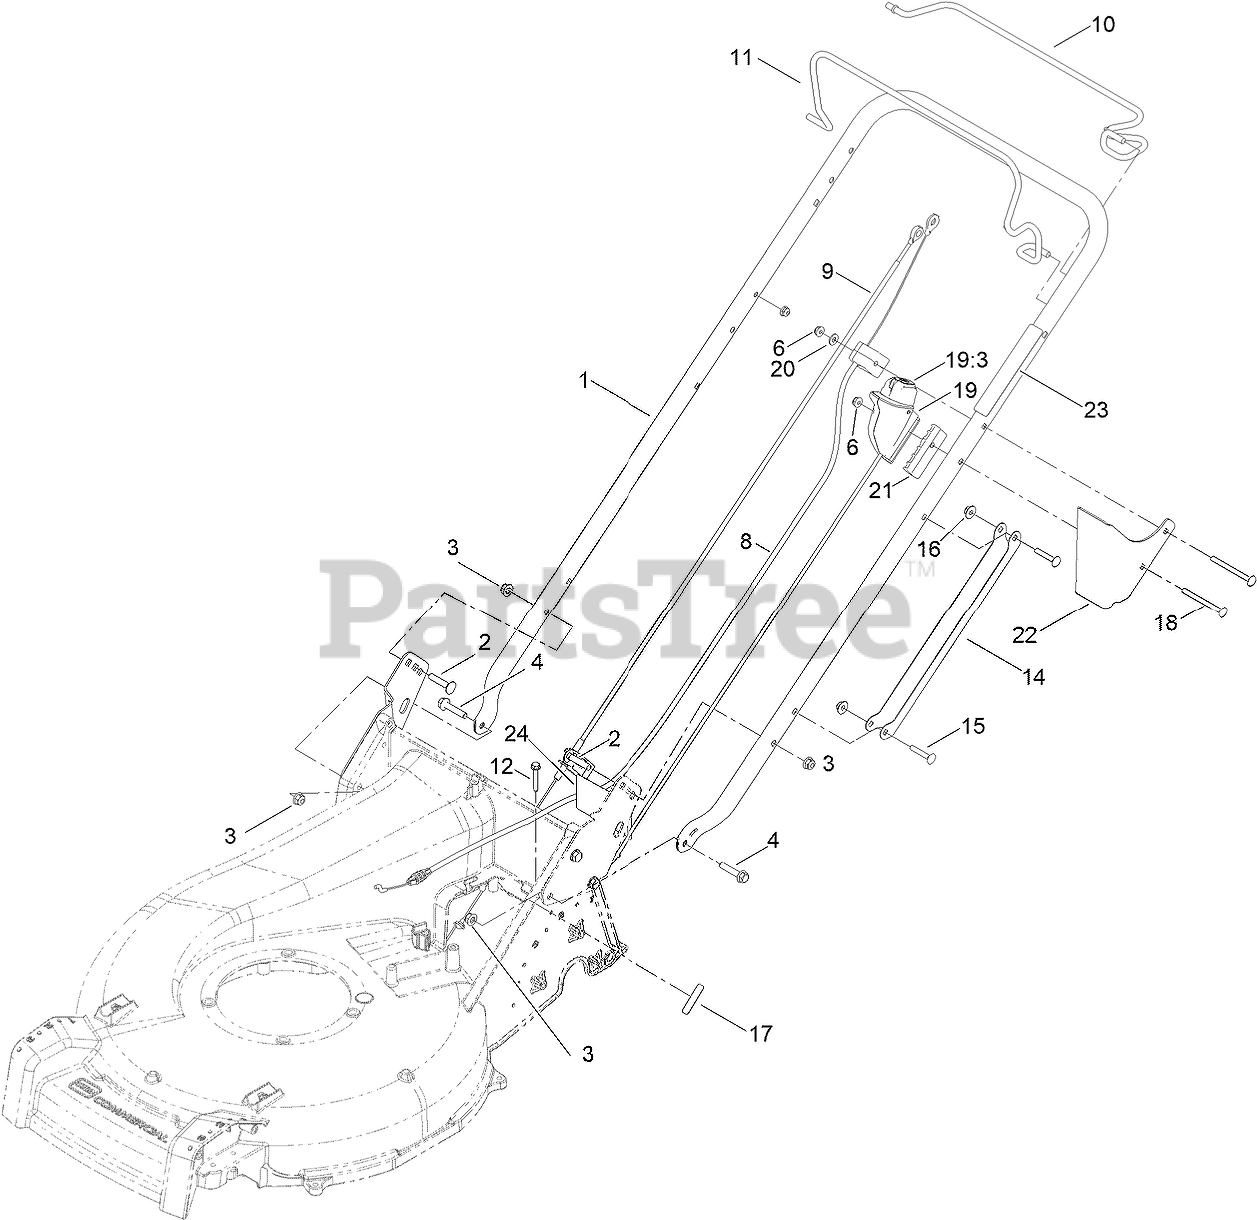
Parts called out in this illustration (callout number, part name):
2	BOLT-CARR
3	NUT-HF, NI
4	SCREW-HHF
6	NUT-HF
8	CABLE-BRAKE, 60V
9	CABLE-TRACTION, 60V
10	BAIL-TRACTION
11	BAIL-BRAKE
12	SCREW-HWH
14	GUARD-CABLE, HANDLE
15	SCREW-CARR
16	NUT-HF
18	SCREW-CARR
19	STARTER SWITCH ASM
19:3	STARTER BUTTON SERVICE ASM
20	WASHER-FLAT
21	SPACER-HOUSING, SWITCH
22	GUARD-HOUSING, SWITCH
23	DECAL-CONTROLS (60V START)
